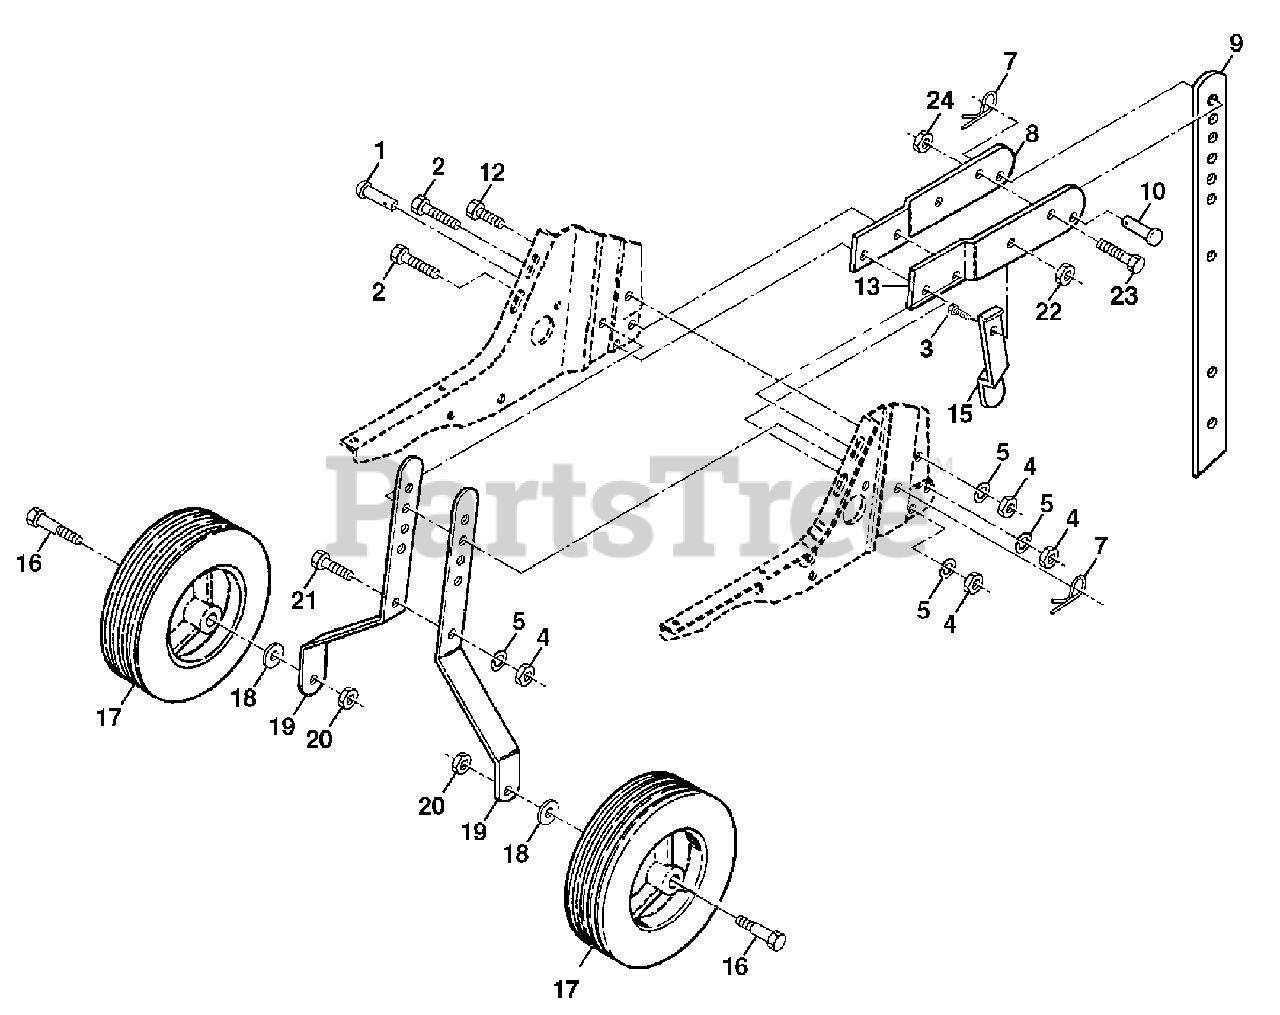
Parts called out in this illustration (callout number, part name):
1	Pin, Clevis
2	Bolt, Hex 5/16-18 x 1-1/4
3	Bolt, Hex 5/16-18 x 3/4
4	Nut, Hex 5/16-18
5	Washer, Lock 5/16
7	Clip, Hairpin
8	Support, Depth Stake, R.H.
9	Stake, Depth
10	Pin, Clevis
12	Bolt, Hex Hd 5/16-18 UNC x 3/4
13	Support, Depth Stake, L.H.
15	Spring, Stake
16	Bolt, Shoulder
18	Washer 13/32 x 13/16 x 11 Ga.
19	Bracket, Wheel
20	Locknut, Crown 3/8-16
21	Bolt, Hex 5/16-18 x 1
22	Locknut, w/insert 5/16-18
23	Bolt Fin Hex 5/16-18 UNC x 1-1/2
24	Nut Lock Hex W/Ins 5/16 x 18 UNC
